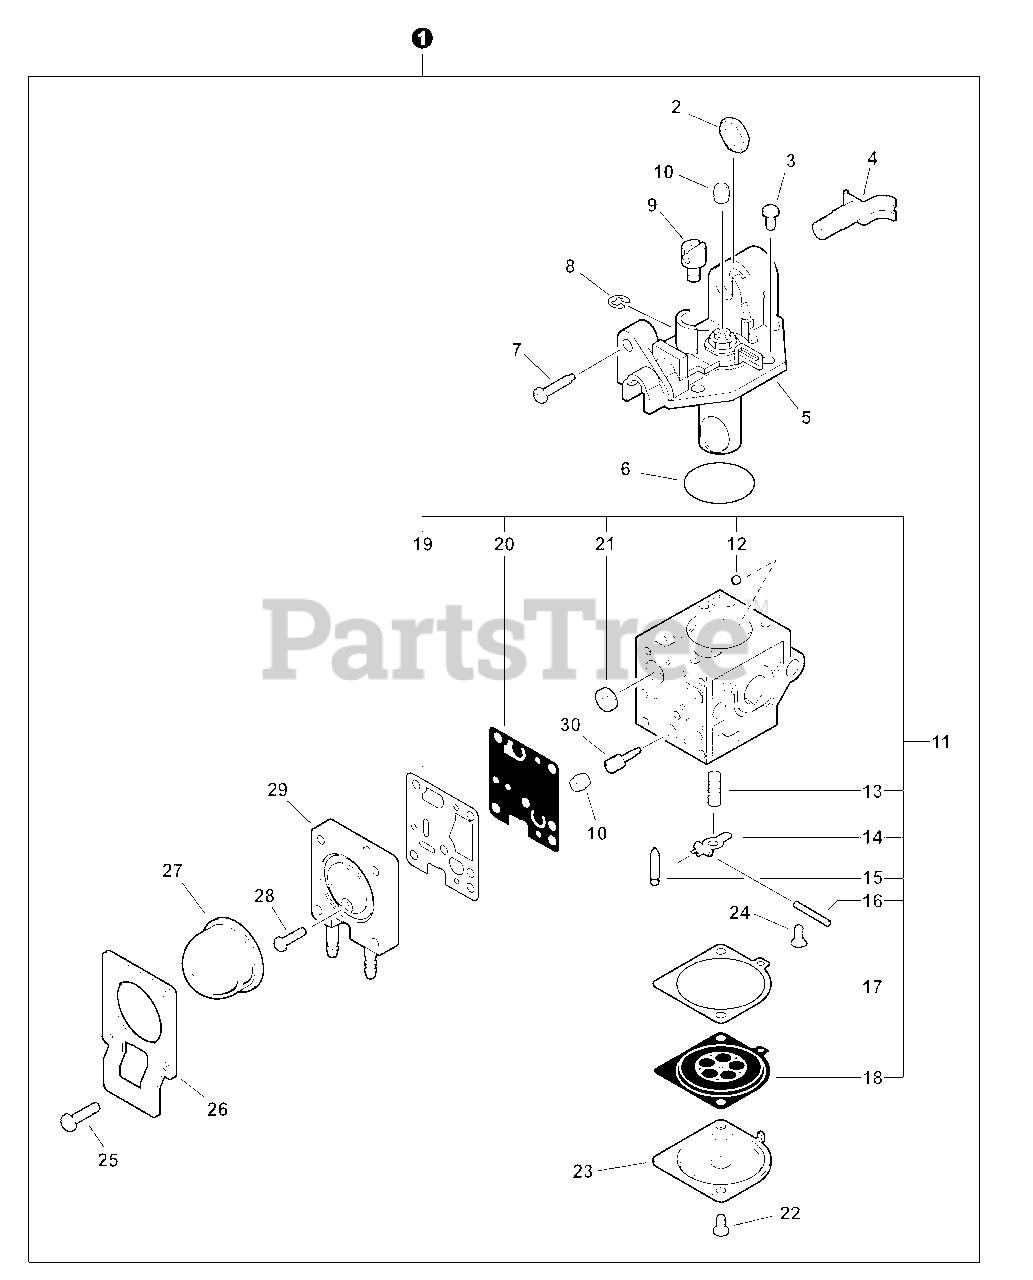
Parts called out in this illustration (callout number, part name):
1	CARBURETOR - RB-K106
4	ADJUSTER, CABLE
5	COVER ASSY, ROTOR
7	SCREW, IDLE ADJUST
11	REPAIR KIT, CARBURETOR
12	GUIDE, ROLLER
13	SPRING, METERING LEVER
14	LEVER, METERING
15	VALVE, INLET NEEDLE
16	PIN, METERING LEVER
17	GASKET, DIAPHRAGM
18	DIAPHRAGM, METERING
19	GASKET, PUMP
20	DIAPHRAGM, PUMP
21	STRAINER
23	COVER, METERING DIAPHRAGM
26	RETAINER, PURGE BULB
27	BULB, PURGE
29	BODY ASSY, PURGE
30	NEEDLE, HIGH SPEED
